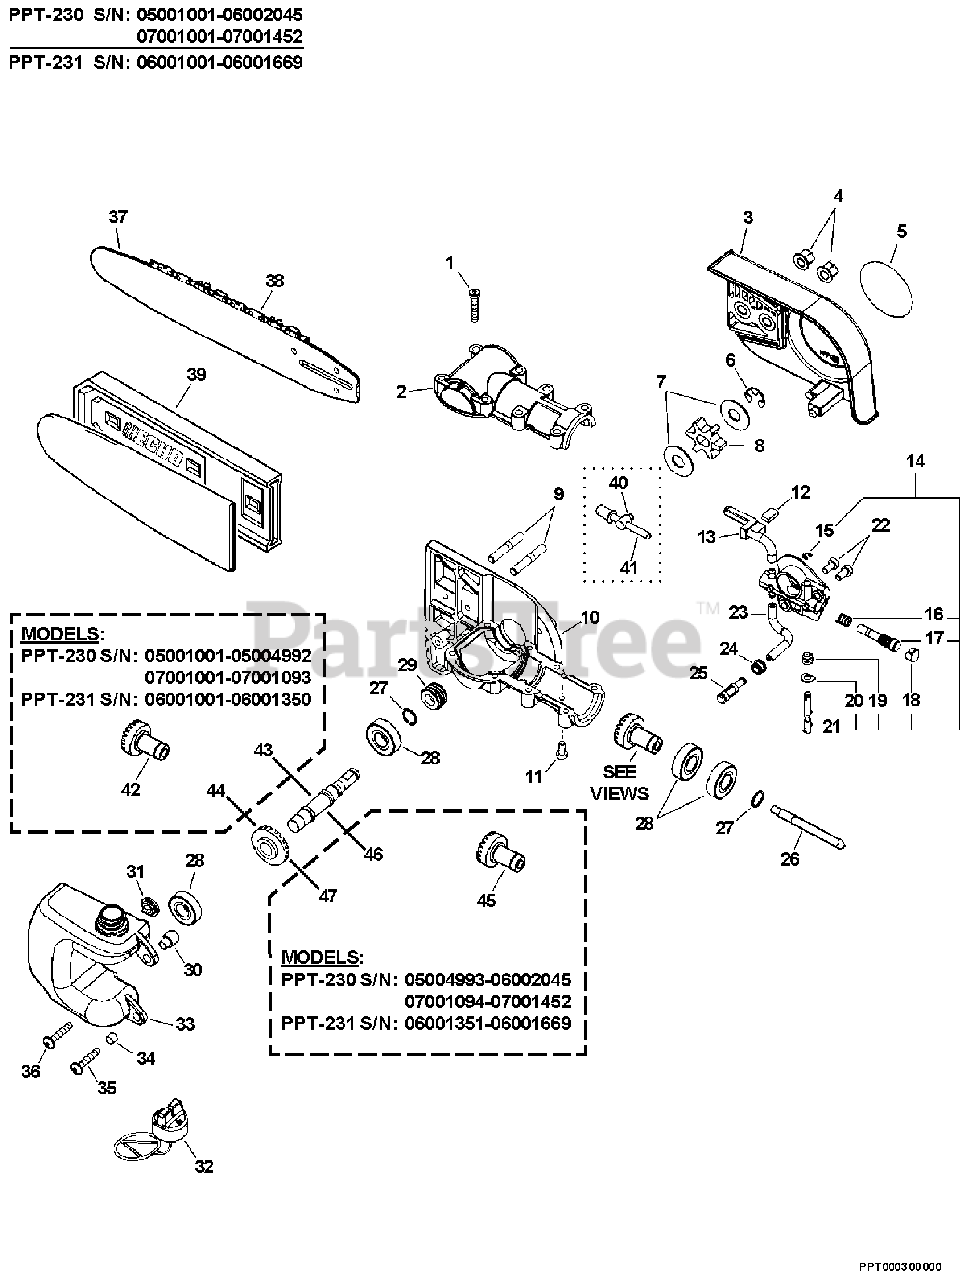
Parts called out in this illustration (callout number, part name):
1	BOLT 5×0.8×25
2	CASE, GEAR - UPPER Ø35
3	GUARD, SPROCKET
4	NUT, FLANGE M6
5	LABEL - ECHO
6	RING, RETAINING Ø0.300
7	WASHER 10.2×24.5×1.2
8	SPROCKET, DRIVE
9	BOLT, STUD 6
10	CASE ASSY, LOWER GEAR
11	BOLT 5×10
12	PAD, FOAM
13	PIPE, OIL OUTLET
14	AUTO-OILER ASSY
17	PLUNGER ASSY
18	CAP, OIL PUMP
21	ADJUSTER, OILER
22	BOLT 5×10
23	PIPE, IMPULSE 3×6×75
24	GROMMET
25	FILTER, OIL
26	CONNECTOR, DRIVE SHAFT
27	RING, SNAP Ø12
28	BEARING, BALL
29	GEAR, WORM
30	COLLAR 6
31	VENT ASSY
32	CAP ASSY, OIL
33	TANK, OIL
34	SPACER 6.2×7.8×6
35	SCREW 5×16 MM
36	SCREW 5×28
37	GUIDE BAR - 10" -- INTENZ
38	SAWING CHAIN - 91VS - 10" -- LOW PROFILE
39	SCABBARD 10"
40	TENSIONER, CHAIN
41	BOLT 5
42	GEAR, BEVEL
43	SHAFT, GEAR
44	GEAR, BEVEL
45	GEAR, BEVEL
46	SHAFT, GEAR
47	GEAR, BEVEL
